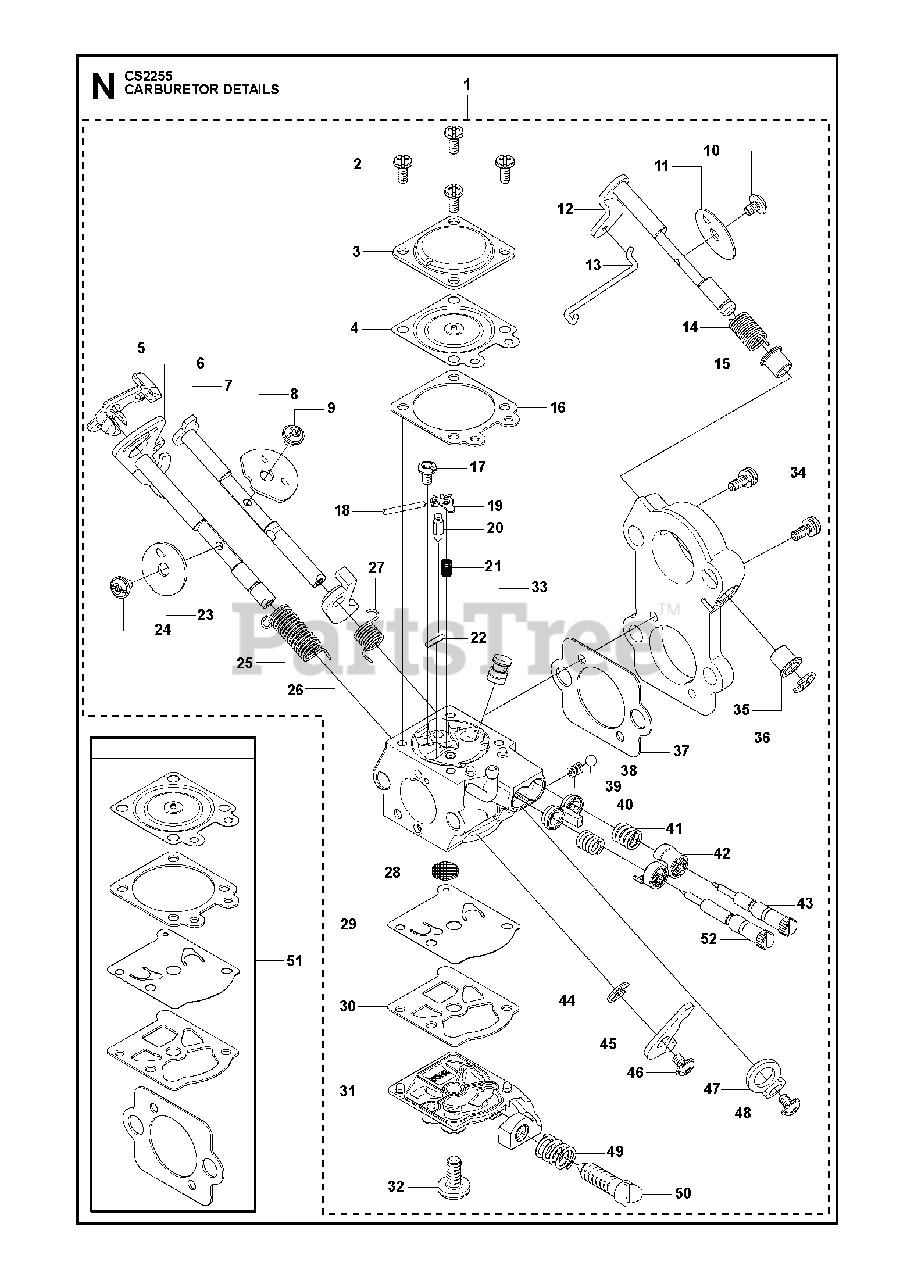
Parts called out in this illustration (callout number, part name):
1	CARBURETOR
2	SCREW
3	DIAPHRAGM COVER
4	DIAPHRAGM
5	BUCKLE
6	SHAFT
7	SHAFT
8	VALVE
9	SCREW
10	SCREW
11	CHOKE FLAP
12	SHAFT
13	ROD
14	SPRING
15	SLEEVE
16	GASKET
17	SCREW
18	FULCRUM PIN
19	LEVER
20	INLET NEEDLE
21	SPRING
22	PLUG
24	SCREW
25	SPRING
26	LEVER
27	SPRING
28	FUEL INLET SCREEN
29	DIAPHRAGM, FUEL PUMP
30	GASKET
31	COVER
32	SCREW
33	NOZZLE ASSY
34	SCREW
35	SLEEVE
36	E CLIP
37	GASKET
39	SPRING
41	SPRING
42	LIMITER CAP
43	NEEDLE
44	E CLIP
45	LEVER
46	SCREW.
47	PLATE
48	SCREW.
49	SPRING
50	SCREW
51	GASKET SET
52	NEEDLE
